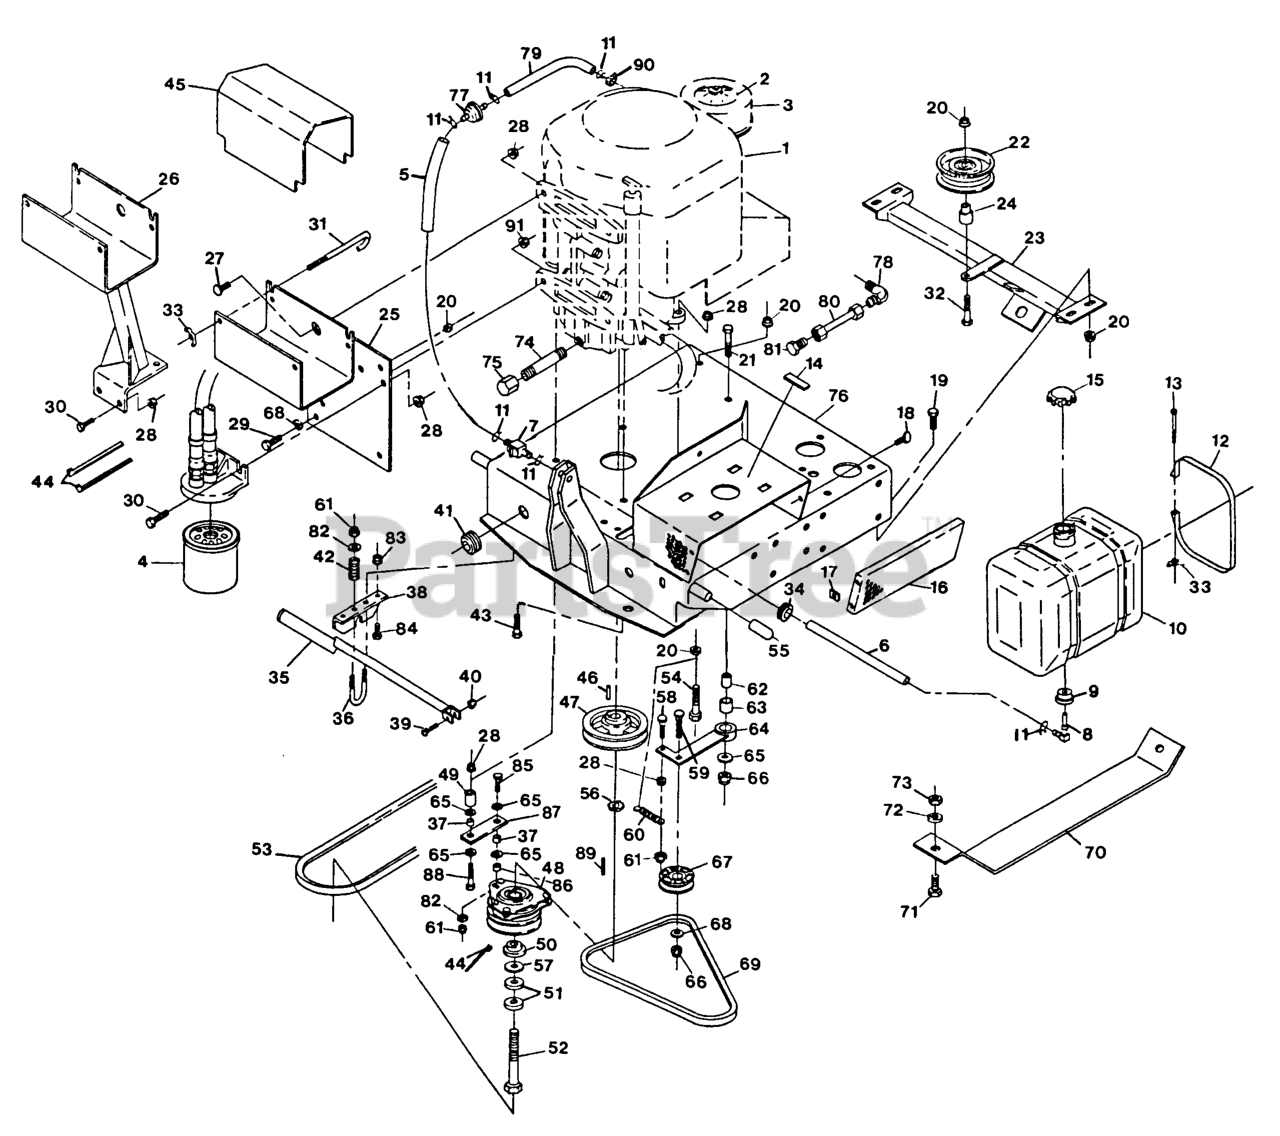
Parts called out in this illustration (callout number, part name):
1	Engine - 18 Hp Kohler
2	Air Filter
3	Foam Precleaner,
4	Oil Filter
5	LINE-FUEL
7	VALVE-FUEL
8	ELBOW-TANK, FUEL
11	CLAMP
14	PAD,PLASTIC TANK
15	CAP-FUEL
17	NUT,RETNR UTYP 1/4-20
18	SCREW,REGTHMB,
23	WLD,CROSSMEMBER
24	BUSHING,IDLER
31	BOLT - HOLD DOWN
33	WINGNUT
34	GROMMET
37	SPACER,CLUTCH ANCHOR
40	NUT-LOCK, HH
41	GROMMET
42	SPRING-COMPRESSION
44	TIE-PLASTIC
46	KEY,MACH 1/4X1/4X2-5/8
47	SHEAVE,4.25 OD A
51	WASHER-SPRING
53	BELT-DK DR FMD-60/TR
55	GRIP-LEVER, DRIVE
60	SPRING,EXTENSION
62	BUSHING,STEEL
63	BUSHING,IDLER ARM
64	WLD,IDLER ARM HYDRO
67	IDLER,PULLEY
69	BELT,A TRANS DRIVE
70	PLATE-SKID
79	HOSE-FUEL
89	KEY
90	CLAMP-HOSE
